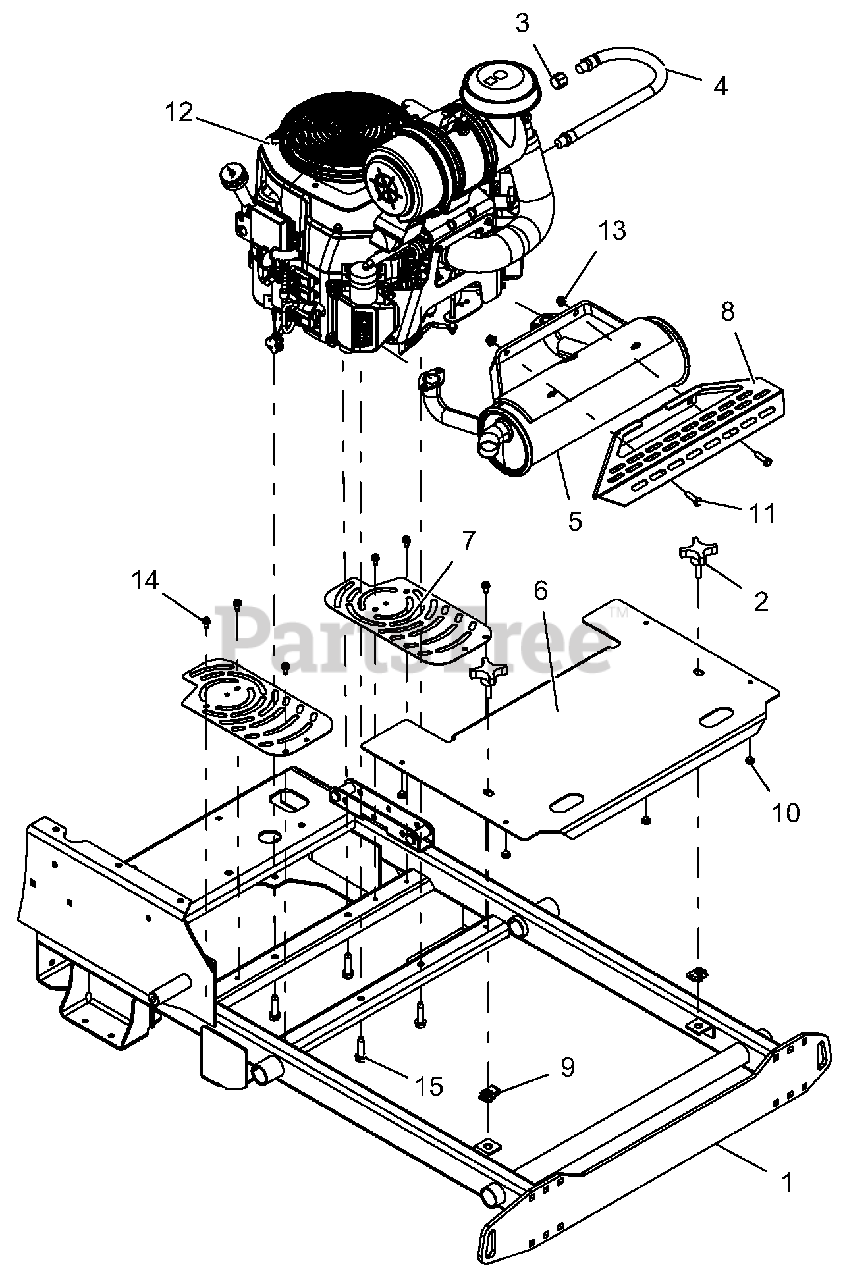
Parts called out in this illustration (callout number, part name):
1	WLDMT, FRAME PROSTANCE
2	KNOB, 3/8 x 1.25 - 4 PRONG
3	PIPE, CAP 3/8 NPT FEMALE
4	DRAIN, M20 OIL
5	MFLR, KOHLER
6	SHIELD, FRONT PRO-STANCE - RED
7	GUARD, FAN
8	GUARD, HEAT SHIELD - BLACK
9	NUT, RTNR .375-16 x .37
10	BUMPER GROMMET .125 x .25 REV
11	BLT-HEX .31-18 x 1.00 GR5 YWZC
12	ENGINE, KOHLER EFI ECV740
13	NUT-LK-NYL-FLG .31-18 YWZC
14	SCR-TAP .25-20 x .50 HWH TR YWZ
15	SCR-TAP .38-16 x 1.50 HWH TR YZ
